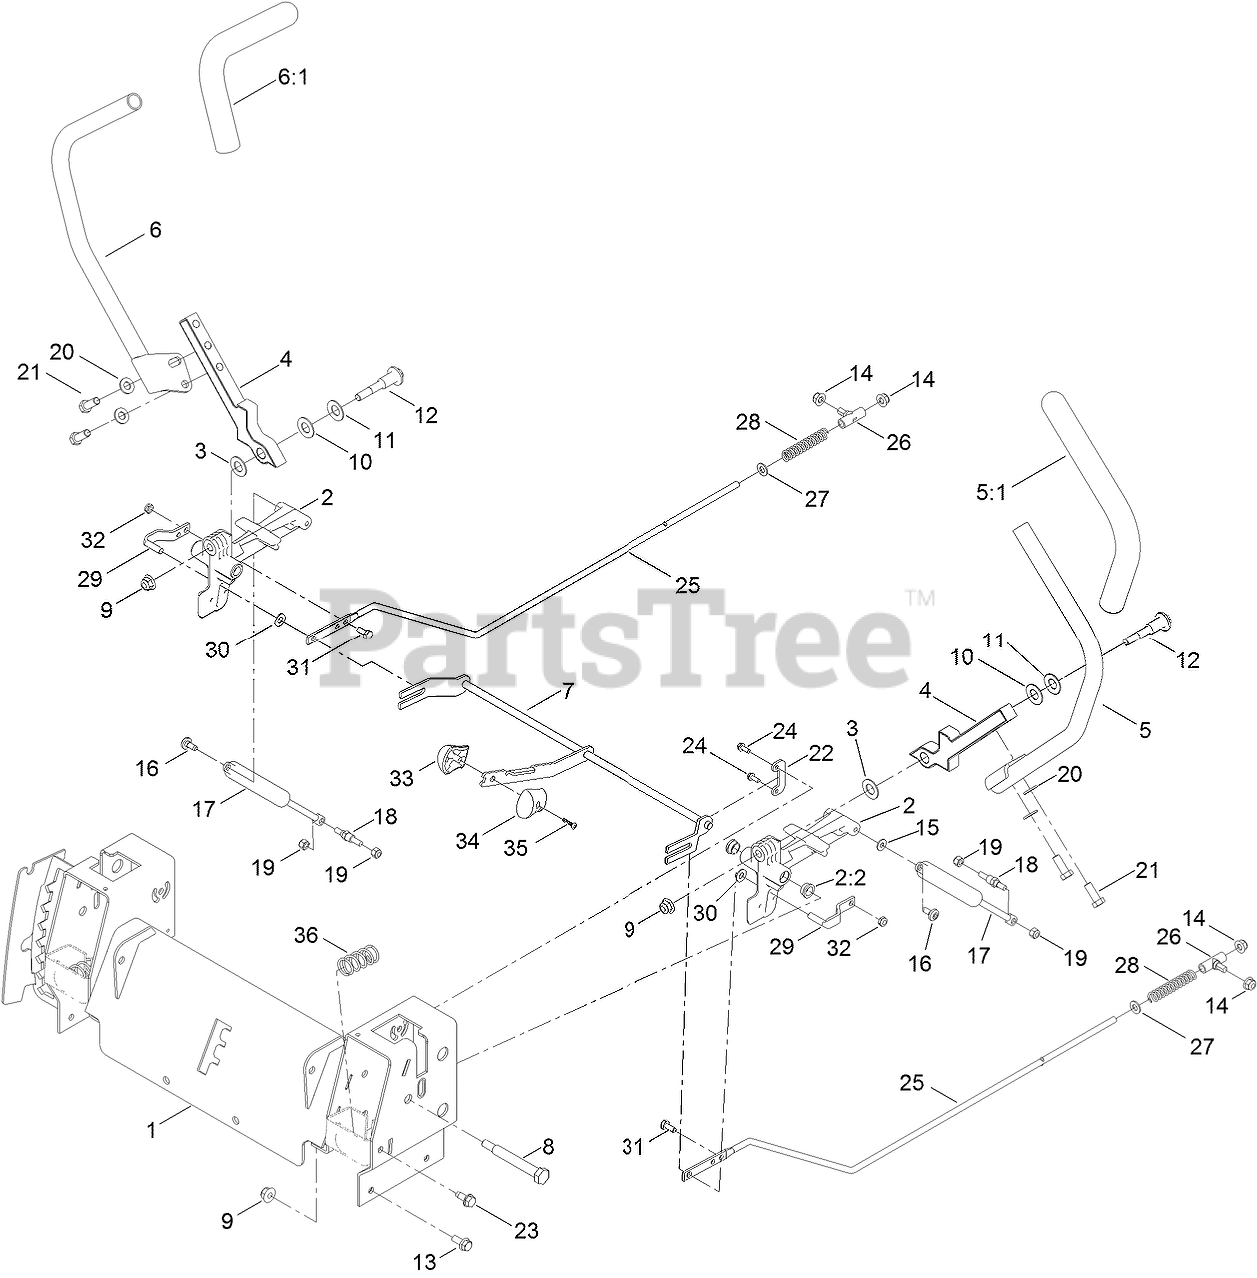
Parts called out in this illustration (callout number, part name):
1	CONTROL BOX ASM
2	ACTUATOR ARM ASM
2:2	BUSHING-FLANGE
3	WASHER-NYLON
4	ARM-CONTROL
5	HANDLE-CONTROL, LH
6	HANDLE-CONTROL, RH
7	SPEED CONTROL ASM
8	BOLT-PIVOT
9	NUT-HF, NI
10	WASHER
11	WASHER-BELLEVILLE
12	BOLT-PIVOT
13	SCREW-HHF
14	NUT-HF, NI
15	WASHER
16	SCREW-SHOULDER
17	DAMPER
18	STUD-DAMPER
19	NUT-LOCK, NI
20	WASHER-FLAT
21	SCREW-HH
22	RETAINER
23	SCREW-HWHTF
24	SCREW-TAPTITE
25	ROD-HYDRO
26	MOUNT-ROD, HYDRO
27	WASHER-PLAIN
28	SPRING-RETURN, NEUTRAL
29	PIN-ROD, HYDRO
30	SPACER-NYLON
31	SCREW-HH
32	NUT-LOCK, NI
33	KNOB-RH
34	KNOB-LH
35	SCREW-PPH
36	SPRING-RETURN
